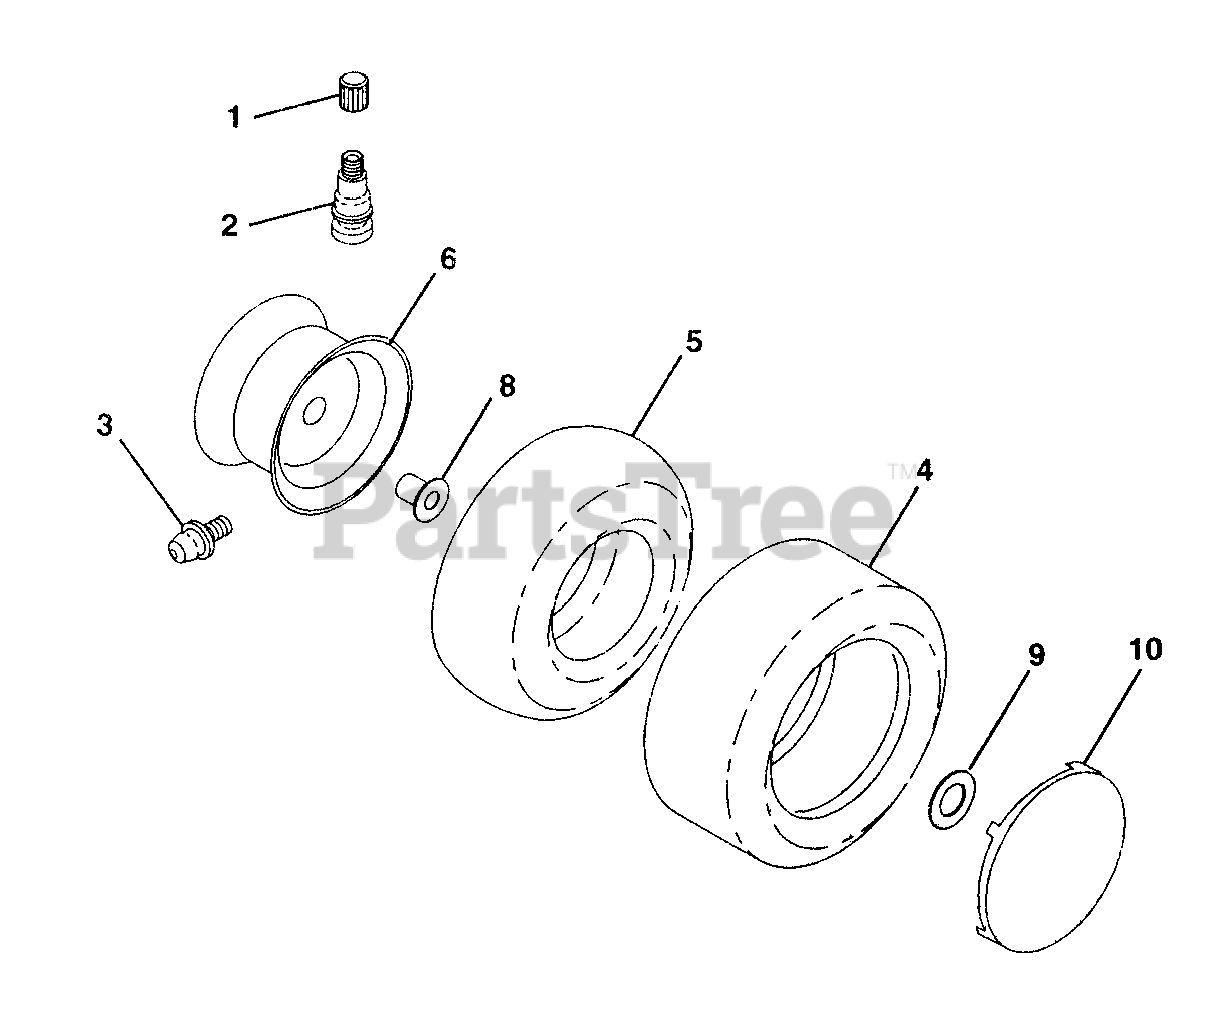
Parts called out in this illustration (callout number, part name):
1	Cap, Valve Stem
2	Stem, Valve
3	Fitting, Grease (Front Wheels Only)
4	Tire, Front
4	Tire, Rear
5	Tube, Front Tire
5	Tube, Rear Tire
6	Rim, Front
8	Bearing Flange
9	Washer 25/32 x 1-5/8 x 16 Gauge
10	Cover, Front Wheel, 6"
10	Cover, Rear Wheel, 8"
